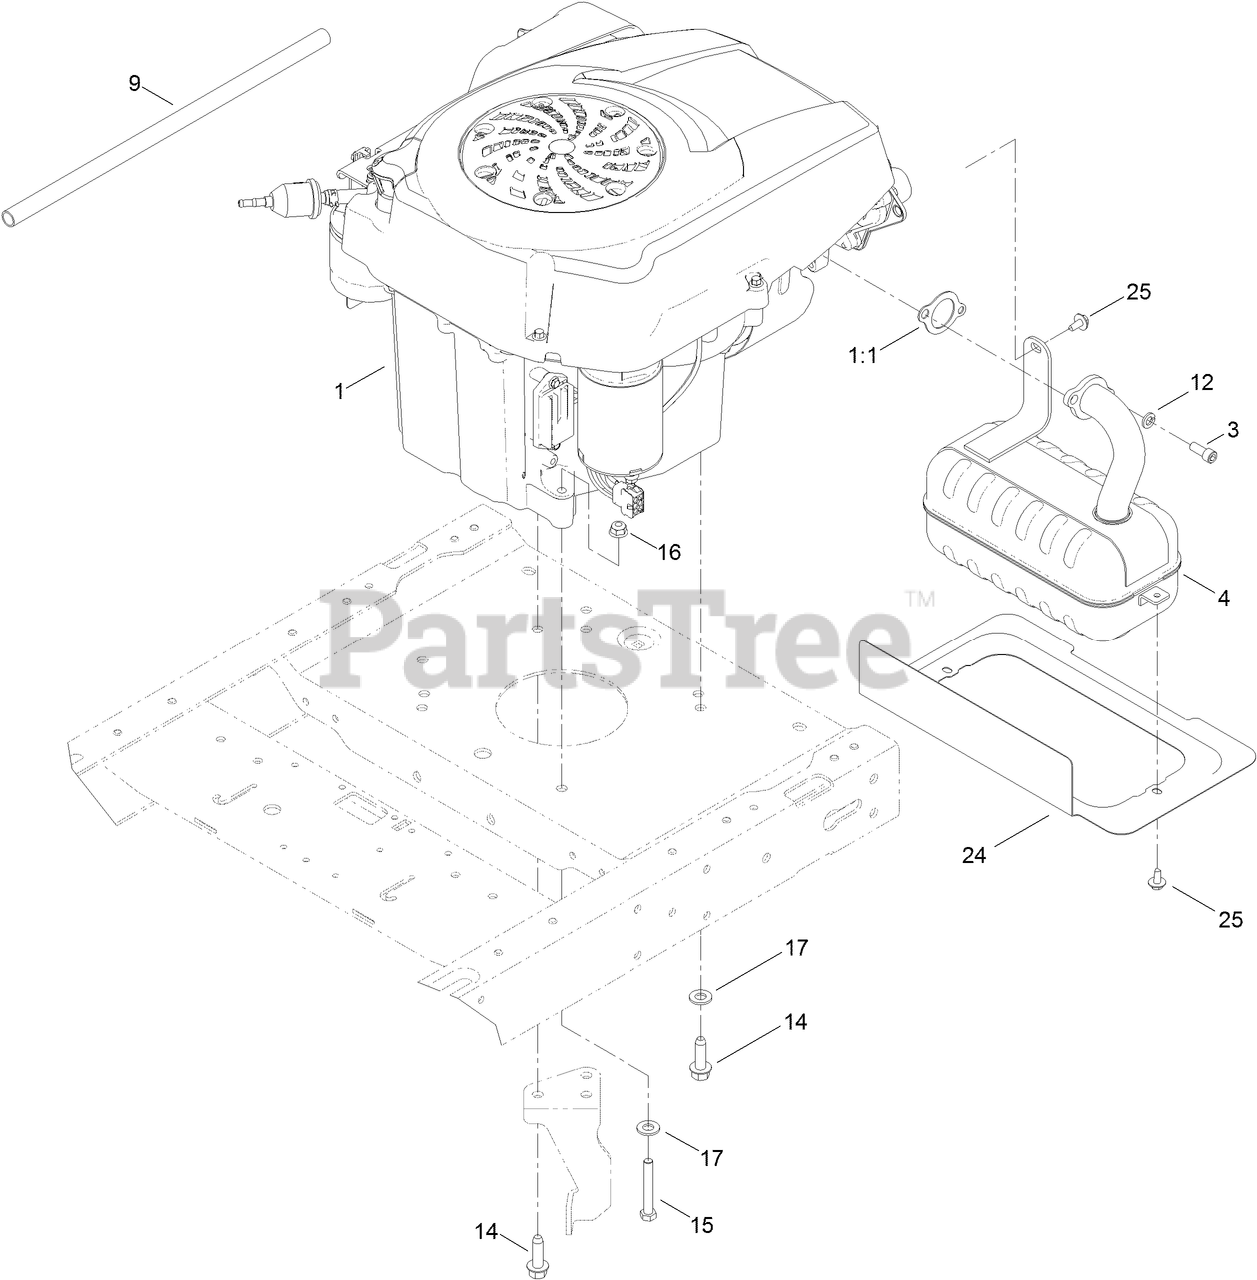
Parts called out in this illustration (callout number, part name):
1:1	GASKET-EXHAUST
3	SCREW-HSH
4	MUFFLER-KOHLER
9	TUBE-DRAIN, OIL
12	WASHER-LOCK
14	SCREW-THD
15	SCREW-HH
16	NUT-HF, NI
17	WASHER-FLAT
24	SHIELD-HEAT
25	SCREW-HHFTF
